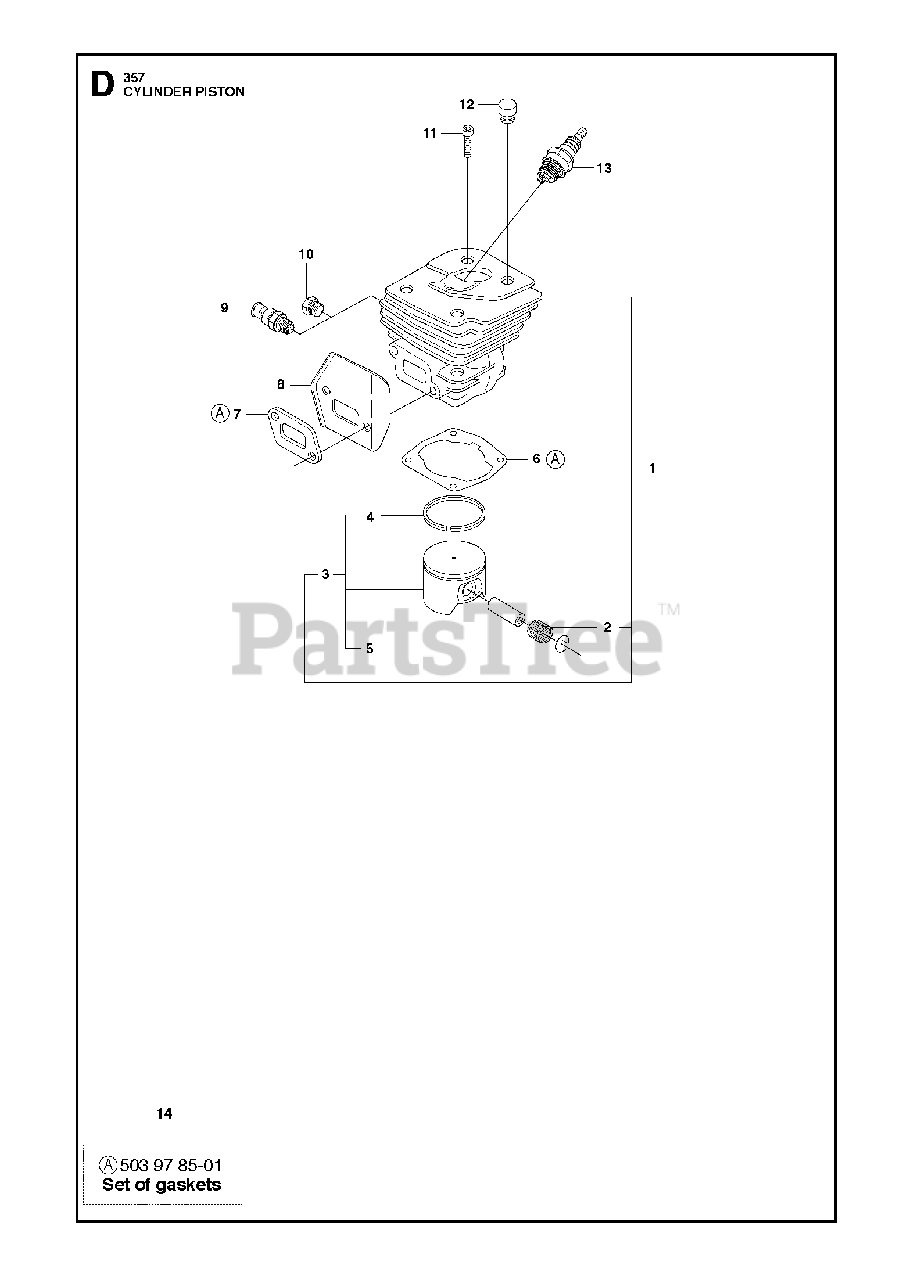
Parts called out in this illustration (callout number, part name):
2	SUPPORT BUSHING
3	PISTON ASSY
4	PISTON RING
5	WRIST PIN CLIP
6	GASKET
7	GASKET
8	HEAT DEFLECTOR
9	DECOMPRESSION VALVE
10	CYLINDER PLUG
11	SCREW MC6S 5X25
13	SPARK PLUG RCJ7Y
14	GASKET SET
